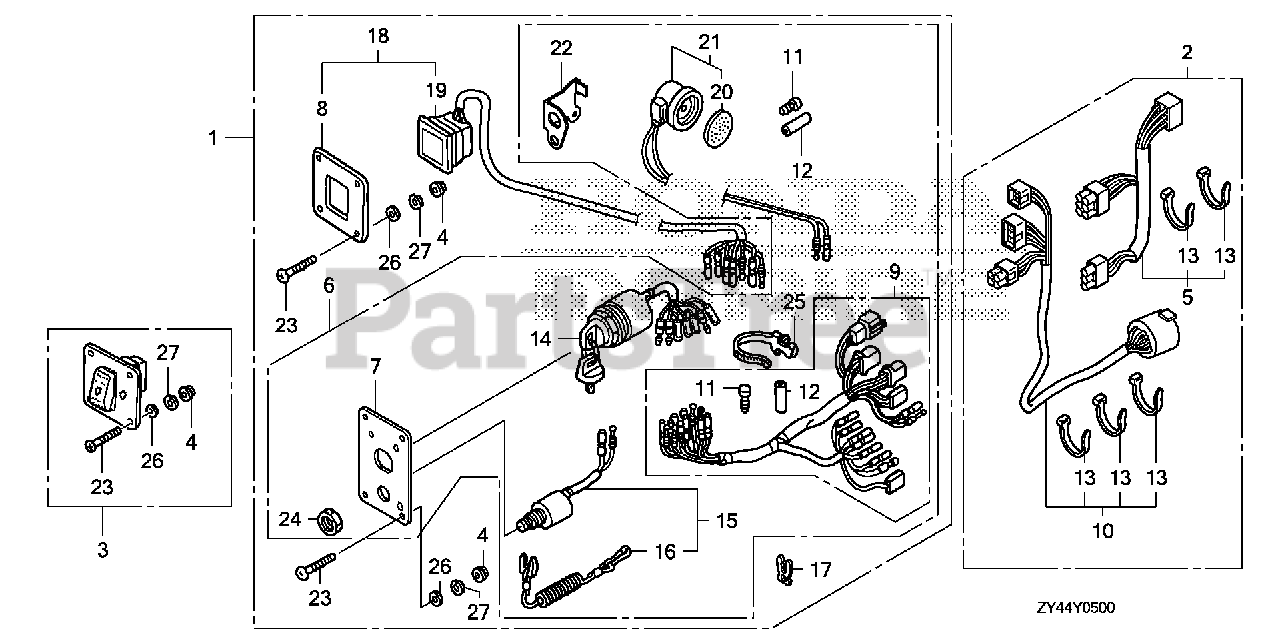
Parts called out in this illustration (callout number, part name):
1	PANEL KIT, SWITCH (4-LED) (B)
2	CABLE SET, PANEL INDICATOR (20FT)
2	CABLE SET, PANEL INDICATOR (25FT)
2	CABLE SET, PANEL INDICATOR (30FT)
3	SWITCH KIT, LIGHT
4	NUT, FLANGE (5MM)
5	WIRE ASSY., INDICATOR (20FT)
5	WIRE ASSY., INDICATOR (25FT)
5	WIRE ASSY., INDICATOR (30FT)
6	PANEL ASSY., SWITCH
7	PANEL, CONTROL
8	PANEL, CONTROL
9	HARNESS ASSY., SWITCH PANEL
10	CABLE ASSY., SWITCH PANEL (25FT) (NHK MEC)
10	CABLE ASSY., SWITCH PANEL (20FT)
10	CABLE ASSY., SWITCH PANEL (25FT)
10	CABLE ASSY., SWITCH PANEL (30FT)
11	PLUG, CONNECTOR (INNER)
12	PLUG, CONNECTOR (OUTER)
13	TIE, CABLE (2.4X92) (NATURAL)
14	SWITCH ASSY., COMBINATION
15	SWITCH ASSY., EMERGENCY STOP
16	WIRE, EMERGENCY
17	CLIP, EMERGENCY LOCK
18	PANEL ASSY., INDICATOR (4-LED)
19	LAMP ASSY., INDICATION (4-LED)
20	PLATE, TURN SIGNAL BUZZER
21	BUZZER, WARNING
22	BRACKET, BUZZER
23	SCREW, PAN (5X40)
24	NUT, HEX. (16MM)
25	BAND, WIRE HARNESS (150MM) (NATURAL)
26	WASHER, PLAIN (5MM)
27	WASHER, SPRING (5MM)
